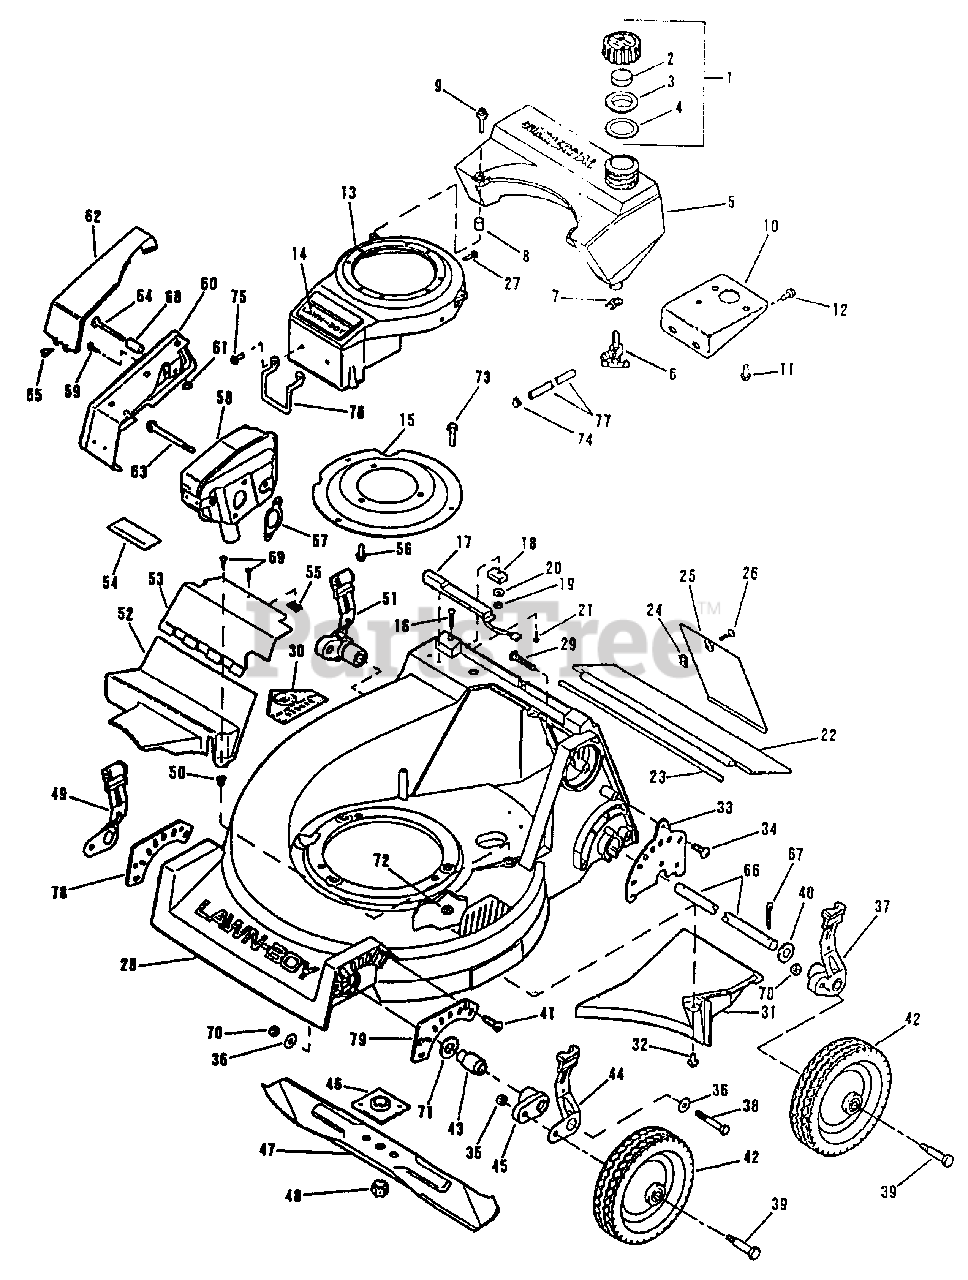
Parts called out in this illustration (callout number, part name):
1	Fuel Cap Assembly
2	Baffle
3	Cover
4	Gasket
5	Fuel Tank
6	Valve and Screen
7	Clamp
8	Spacer
9	Screw, SEMS-Fuel Tank to Shroud
10	Fuel Tank Mounting Bracket
11	Screw-Fuel Tank to Bracket
12	Screw-Tank Bracket to Block
13	Shroud and Applique Assembly
14	Applique
15	Engine Mounting Plate
16	Screw-Magnet to Housing
17	Bag Interlock Switch
18	Magnet
19	Nut-Magnet to Housing
20	Lockwasher-Magnet to Housing
21	Screw-Interlock Switch to Housing
22	Trailing Shield (ZPRA)
23	Trailing Shield Pivot Rod
24	Speed Nut
25	Access Door
26	Screw-Access Door to Housing
27	Screw-Shroud to Engine
28	Housing Assembly
29	Handle Mounting bolt
30	Decal-Blade Contact Warning
31	Baffle-Chute Floor
32	Screw-Baffle to Housing
33	Height Adjust Plate
34	Screw-Plate to Housing
35	Nut-Front Wheel Bolt (ZPRA)
36	Washer-Front Height Adjust Arm
37	Rear Height Adjust Arm-L.H.
38	Screw-Front Height Adjust Arm
39	Shoulder Bolt-Wheel
40	Washer
41	Flat Head Screw
42	Wheel and Tire Assembly
43	Front Height Adjust Bushing
44	Knob and Spring Assy-Front L.H.
45	Front Height Adjust Arm
46	Collar and Plate
47	21" Blade
48	Nut-Blade
49	Knob and Spring Assy-Front R.H.
50	Grommet
51	Rear Height Adjust Arm-R.H.
52	Lower Drive Cover
53	Upper Drive Cover w/Decal
54	Decal-Warning
55	Speednut
56	Screw-Mounting Plate to Engine
57	Exhaust Gasket
58	Muffler
59	Screw-Muffler Guard
60	Muffler Guard Assembly
61	Pushnut
62	Muffler Cover
63	Screw-Muffler
64	Screw-Muffler Guard
65	Screw-Muffler Guard
66	Height Adjust Pivot Rod
67	Cotter Pin
68	Spacer-Muffler Guard
69	Screw-Drive Cover to Housing
70	Nut (ZPRA)
71	Flat Washer
72	Locknut-Mting Plate to Housing
73	Screw-Mting Plate to Housing
74	Clamp-Fuel Line to Carburetor
75	Hex Flange Head Screw
76	Spark Plug Guard
77	Fuel Line
78	Front Height Adjust Plate-R.H.
79	Front Height Adjust Plate-L.H.
